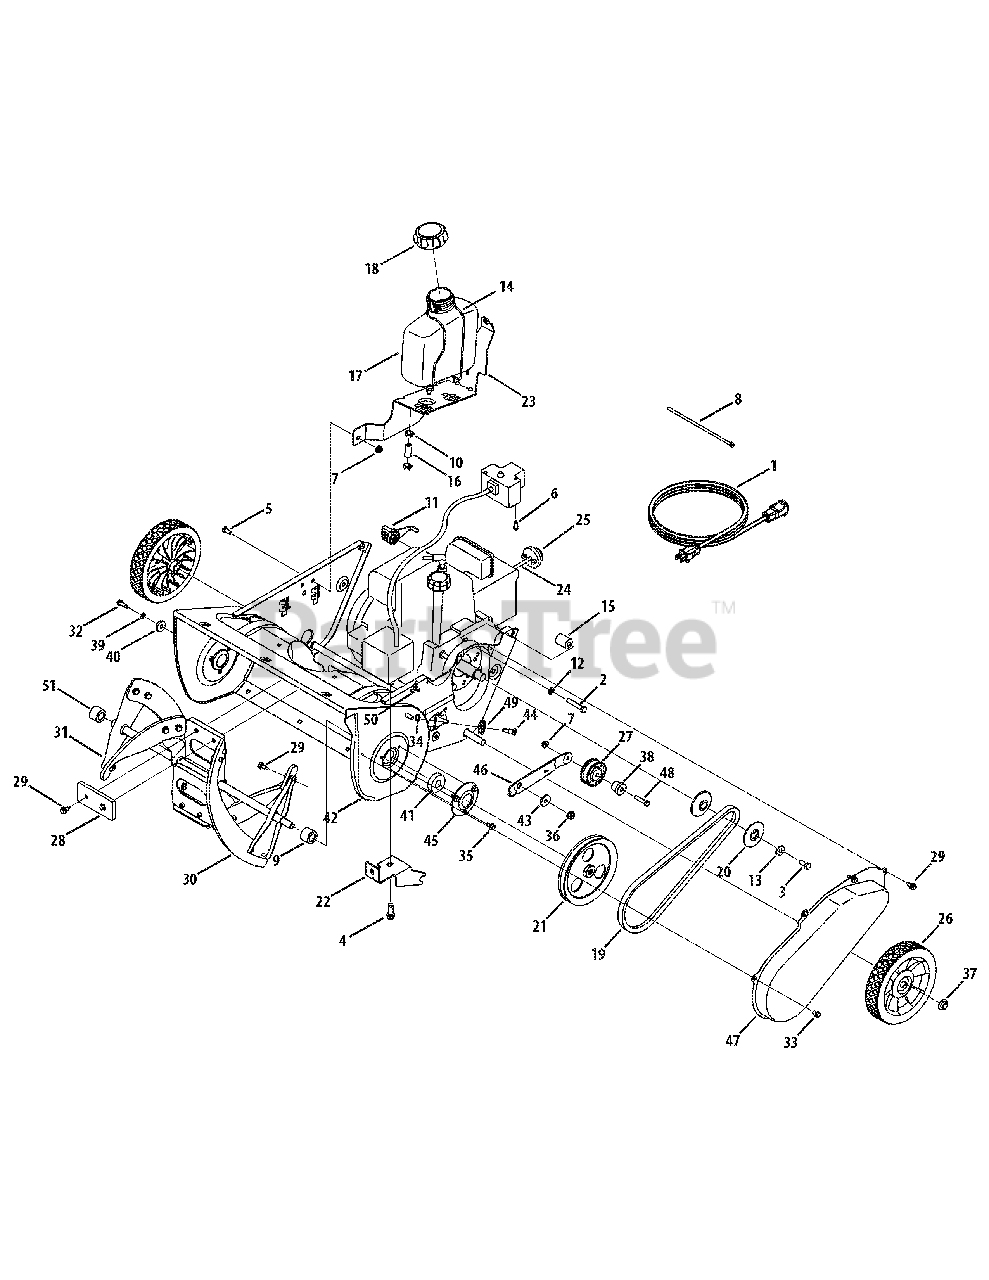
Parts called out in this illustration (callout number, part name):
1	Extension Cord
2	Hex Screw, 5/16-24 x 1.75
3	Hex Screw, 5/16-24 x .75
4	Self Tapping Screw, 3/8-16 x 1
5	Hex Screw, 1/4-20 x .62
6	Screw, #10-16 x .625
7	Hex Flange Lock Nut, 1/4-20
8	Push Mount Cable Tie
9	Spacer, Auger - LH
10	Clamp, Hose
11	Knob, Choke
12	Washer, Lock 5/16
13	Flat Washer .340 x .872 x .060
14	Gas Tank Support Wire
15	Spacer, Engine
16	Hose, Fuel Line
17	Tank, Fuel
18	Cap, Fuel
19	V-Belt, 1/2
20	Pulley Half, .625 ID x 2.25 OD
21	Pulley, 1/2 x 6.0 OD
25	Primer
26	Wheel
27	Idler Pulley (1/4" hole)
28	Rubber Paddle
29	Hex Screw, 1/4-20 x .62
30	Cresent Spiral
32	Hex Screw 1/4-20 x .75 Gr. 5
33	Self-tapping Screw 1/4-20 x .
34	Hex Lock Nut 1/4-28
35	Screw, 1/4-14 x .500"
36	Hex Flange Lock Nut, 5/16-18
37	Push Cap, 1/2"
38	Shoulder Spacer .260 x .785 x .
39	Lock Washer, 1/4
40	Flat Washer .265 x .938 x .120
41	Ball Bearing .625 x 37 x 12
43	Shoulder Spacer .25
44	Carriage Screw 1/4-28
48	Hex Screw, 1/4-20 x 1.00 Gr. 5
49	Cable Roller
50	Extension Spring
51	Spacer, Auger - RH
